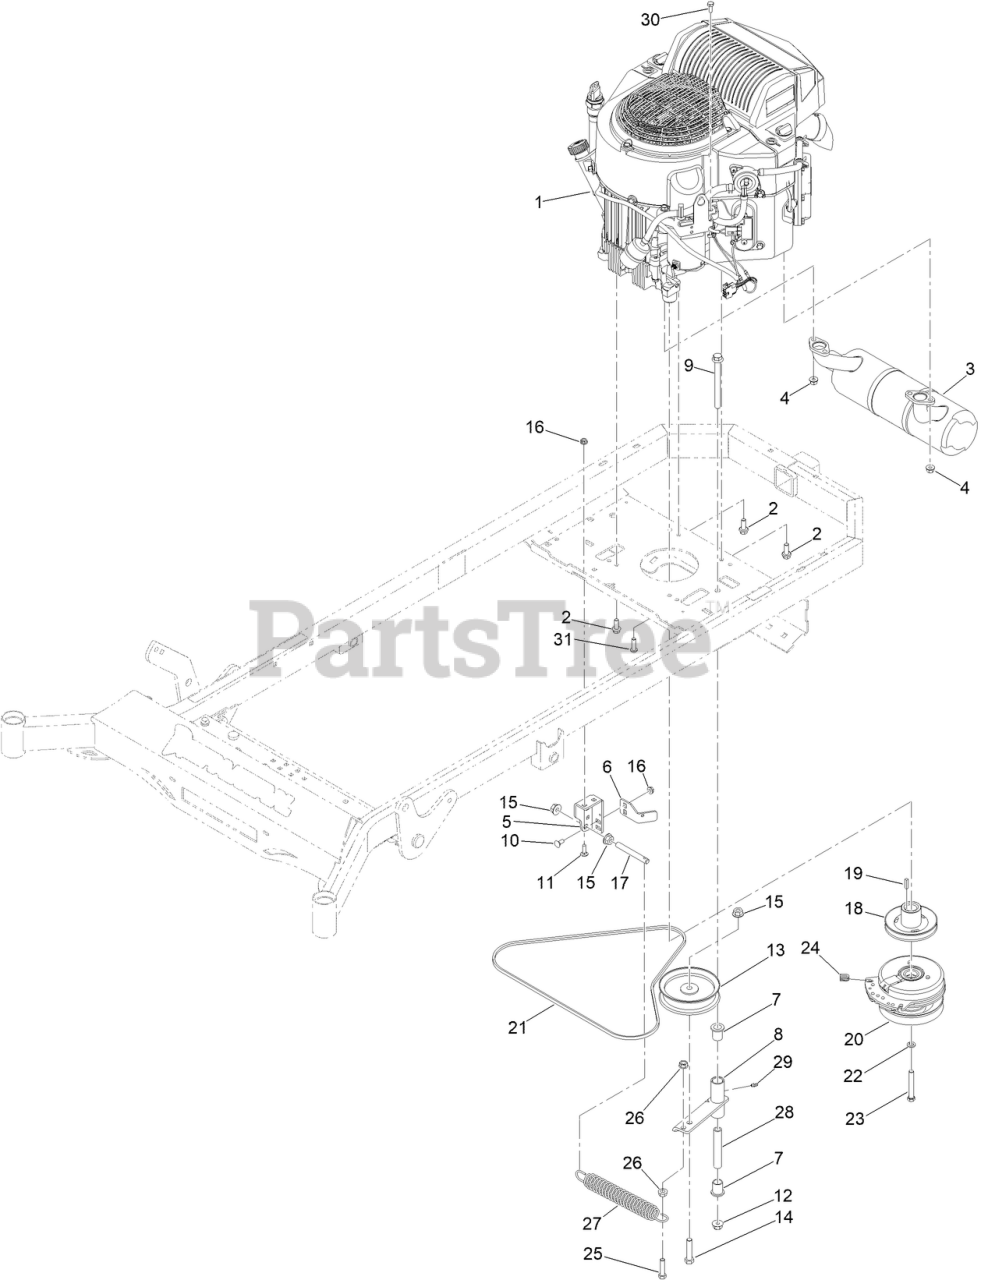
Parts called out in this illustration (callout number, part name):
1	KAWASAKI FT730-CARB ENGINE
2	3/8-16 X 1-1/8 IND HWH W/SERR TRI LOB ZY
3	2019 EXHAUST SYST FOR KAWI FR FS AND FT
4	NUT-HF
5	MWR PUMP IDLER TENSIONING BRKTPAINTED
6	MOWER CLUTCH ANTI ROTATION BRACKET PAINT
7	3/4IN ID X15/16IN OD X 1-1/8IN FLNG BUSH
8	MWR PUMP IDLER ASSY PAINTED
9	1/2-13 X 5-1/2 HEX FLANGE BOLT GR 8 ZY
10	BOLT-CARR
11	BOLT-CARR
12	NUT-LOCK
13	5-3/4IN IDLER PULLEY 7/16IN SPACER ASSY
14	SCREW-HH
15	NUT-HHF
17	MWR PUMP IDLER SPRING TENSIONER
18	MWR HYDRAULIC PUMP DRIVE PULLEY (B-BELT)
20	WARNER PTO CLUTCH
21	TTQ RT PUMP B-BELT (61.25")
22	WASHER-LOCK
23	7/16-20 X 3 HEX C/S GR 8 ZC YELLOW
24	MWR CLUTCH ROTATION STOP BRKT SLEEVE
25	SCREW-HH
26	NUT-HF
27	MWR DECK SPRING
28	MWR INNER IDLER SPACER
29	1/4IN DRIVE TYPE GREASE FITTING YZ
30	M8-1.25 X 20MM HEX FLANGE BOLT ZINC 10.9
31	3/8-16 X 1-1/4 PAN TORX (TRI-LOB) TRS ZC
